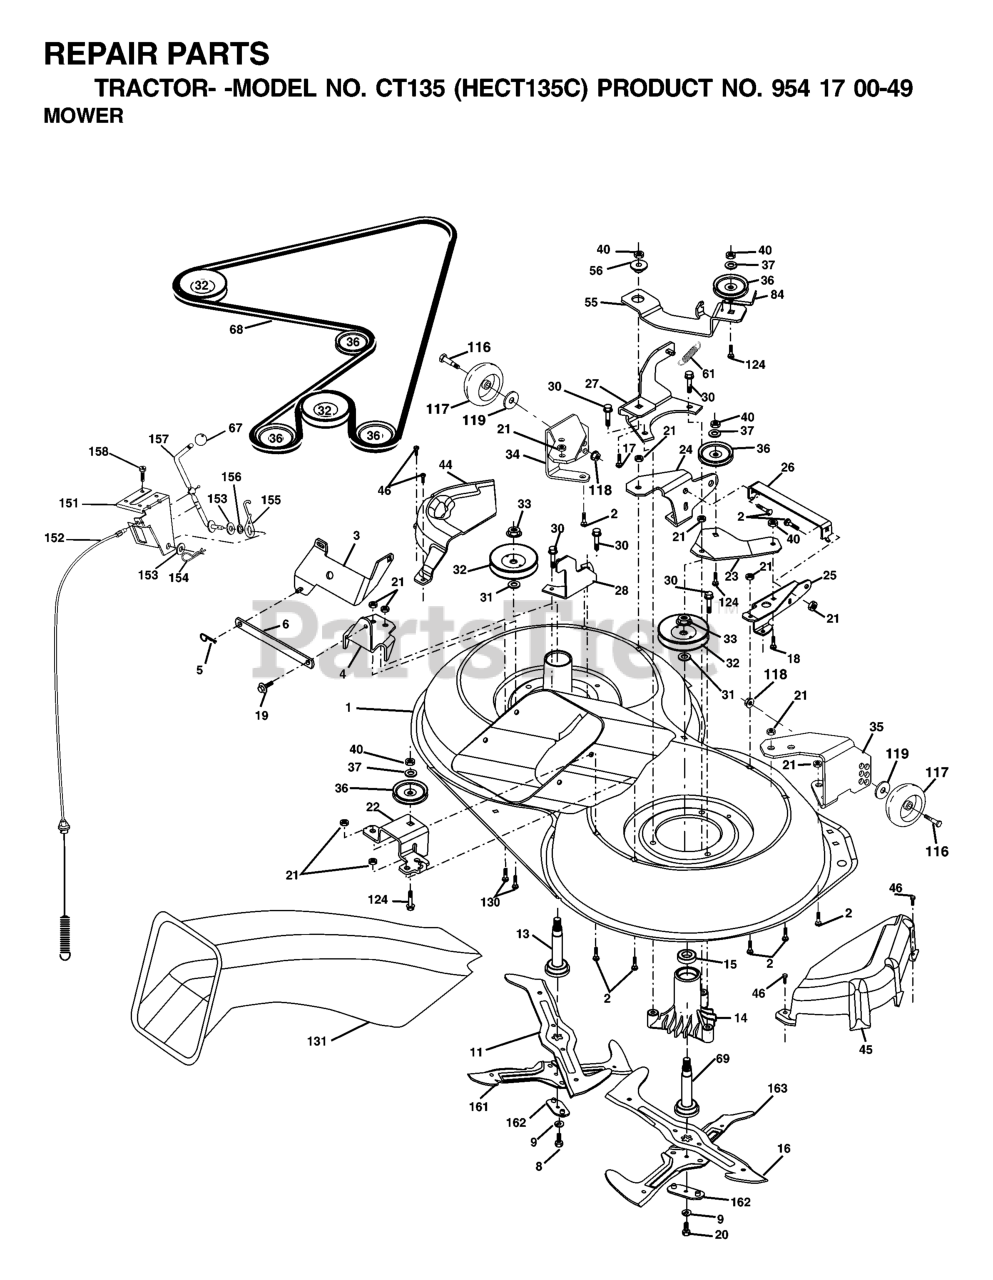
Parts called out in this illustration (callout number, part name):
1	MOWER HOUSING, DECK
2	RP BOLT 5/16-18 X3/4 ZN/YEL GR
5	RETAINER-SPRNG RB
6	BAR.SWAY.92.CRD
8	BOLT.3/8-24X1.25 GR8
9	LOCKWASHER
11	BLADE-LH 5PT STAR(CTH130)
13	SHAFT ASM VENT
14	HOUSING.MANDREL.VENTED (MACHD)
16	BLADE RH 6PT STAR(CTH130)
17	BOLT.3/8-14X1.25
18	BOLT D
19	BOLT SHD 5/16-18
20	BOLT.3/8-24X1.25GR8. LHTHRD
21	LOCKNUT
26	BRACE.SUPT.SUSP.FRT.CRD
30	SCREW, WASHER HEAD
31	WASHER
32	PULLEY, MANDREL
33	NUT, FLG TOPLOCK 9/16"
36	PULLEY.IDLER.4.25
37	WASHER
45	COVER.MANDREL.RH.CRD
46	SCREW.1/4-20X5/8
56	SPACER.RETAINER.MOWER
61	SPRING.TENSION.BELT
67	KNOB T (3/8 HOLE)
68	HEX-BELT
69	SHAFT.ASM.W/LWR.BRG.RH.THREAD
84	KEEPER, BELT IDLER
116	BOLT, SHOULDER
117	WHEEL GAGE DONUT
118	LOCKNUT
119	WASHER.5/16.FLAT.STE.STD.
124	BOLT.3/8-16X1.50
130	BOLT.CARR.SQNK.5/16-18UNC.X3/4
131	CHUTE BAGGER
151	BRACKET.CLUTCH.CABLE
153	WASHER FLAT 3/8"
154	SPRING RETAINER
155	SPRING RETENTION LEVER
156	SPACER.CLUTCH.CABLE
157	ROD CLUTCH CABLE 3/8"
158	SCREW
162	ADAPTER.BLADE.PNT.CSS.36/38/42
